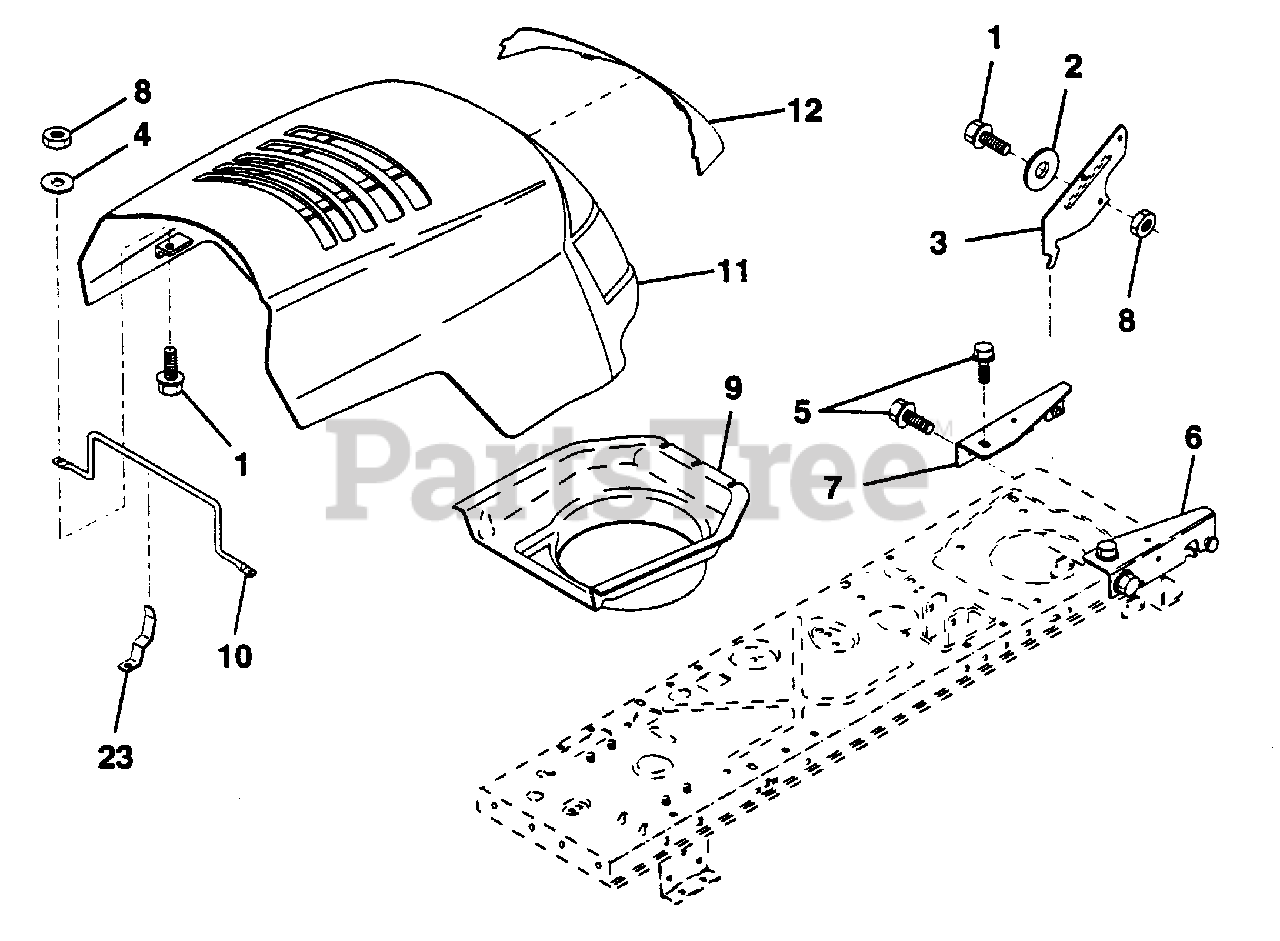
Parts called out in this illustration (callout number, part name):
1	Bolt Fin Hex 1/4-20 x 3/4 (AYP part number)
2	Washer (AYP part number)
3	Bracket Pivot Hood (AYP part number)
4	Washer, Flat 1/4 (AYP part number)
5	Screw Thdrol 5/16-28 x 3/4
6	Bracket Asm. Pivot Hood RH (AYP part number)
7	Bracket Asm. Pivot Hood LH (AYP part number)
8	Locknut W/Insert 1/4-20 (AYP part number)
9	Duct Air Hood (AYP part number)
10	Rod Support (AYP part number)
12	Lens Bar (AYP part number)
23	Latch Hood (AYP part number)
